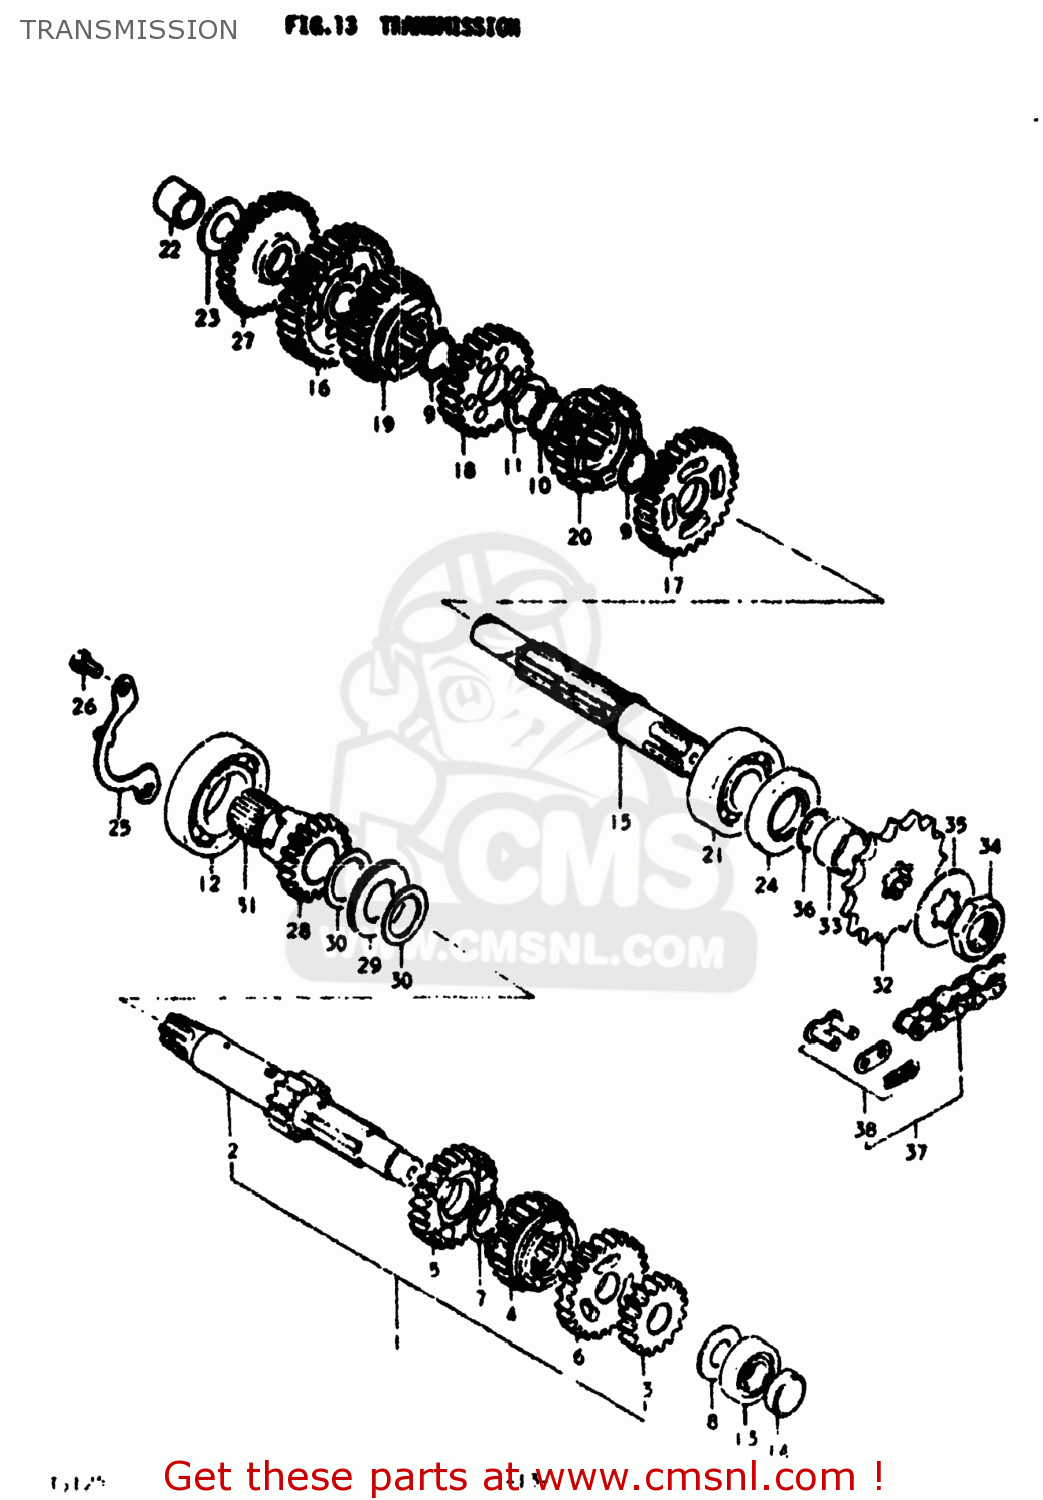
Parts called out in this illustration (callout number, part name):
1	SHAFT,COUNTER
2	SHAFT,COUNTER
3	GEAR,2ND DRIVE
4	GEAR,THIRD DRIVE
5	GEAR,FOURTH DRIVE
6	GEAR,FIFTH DRIVE
7	CIRCLIP
8	WASHER
9	CIRCLIP
10	CIRCLIP
11	WASHER
12	BEARING, RH
13	BEARING
14	PLUG
15	SHAFT,DRIVE
16	GEAR,1ST DRIVEN
17	GEAR,SECOND DRIVEN
18	GEAR,THIRD DRIVEN
19	GEAR,FOURTH DRIVEN
20	GEAR,FIFTH DRIVEN
21	BEARING
22	BUSH
23	WASHER
24	OIL SEAL (25X44X7)
25	RETAINER,CNTR SHAFT BEARING
26	SCREW
27	GEAR,KICK STARTER IDLE
28	GEAR,KICK STARTER DRIVE
29	BEARING
30	WASHER(21X30X0.8)
31	BEARING(19.2X23.2X19)
32	SPROCKET,ENGINE
33	SPACER(20X25X12.5)
34	NUT
35	WASHER,LOCK
36	O RING(D:1,ID:19.5)
37	CHAIN ASSEMBLY,DRIVE
38	JOINT ASSEMBLY,CHAIN
